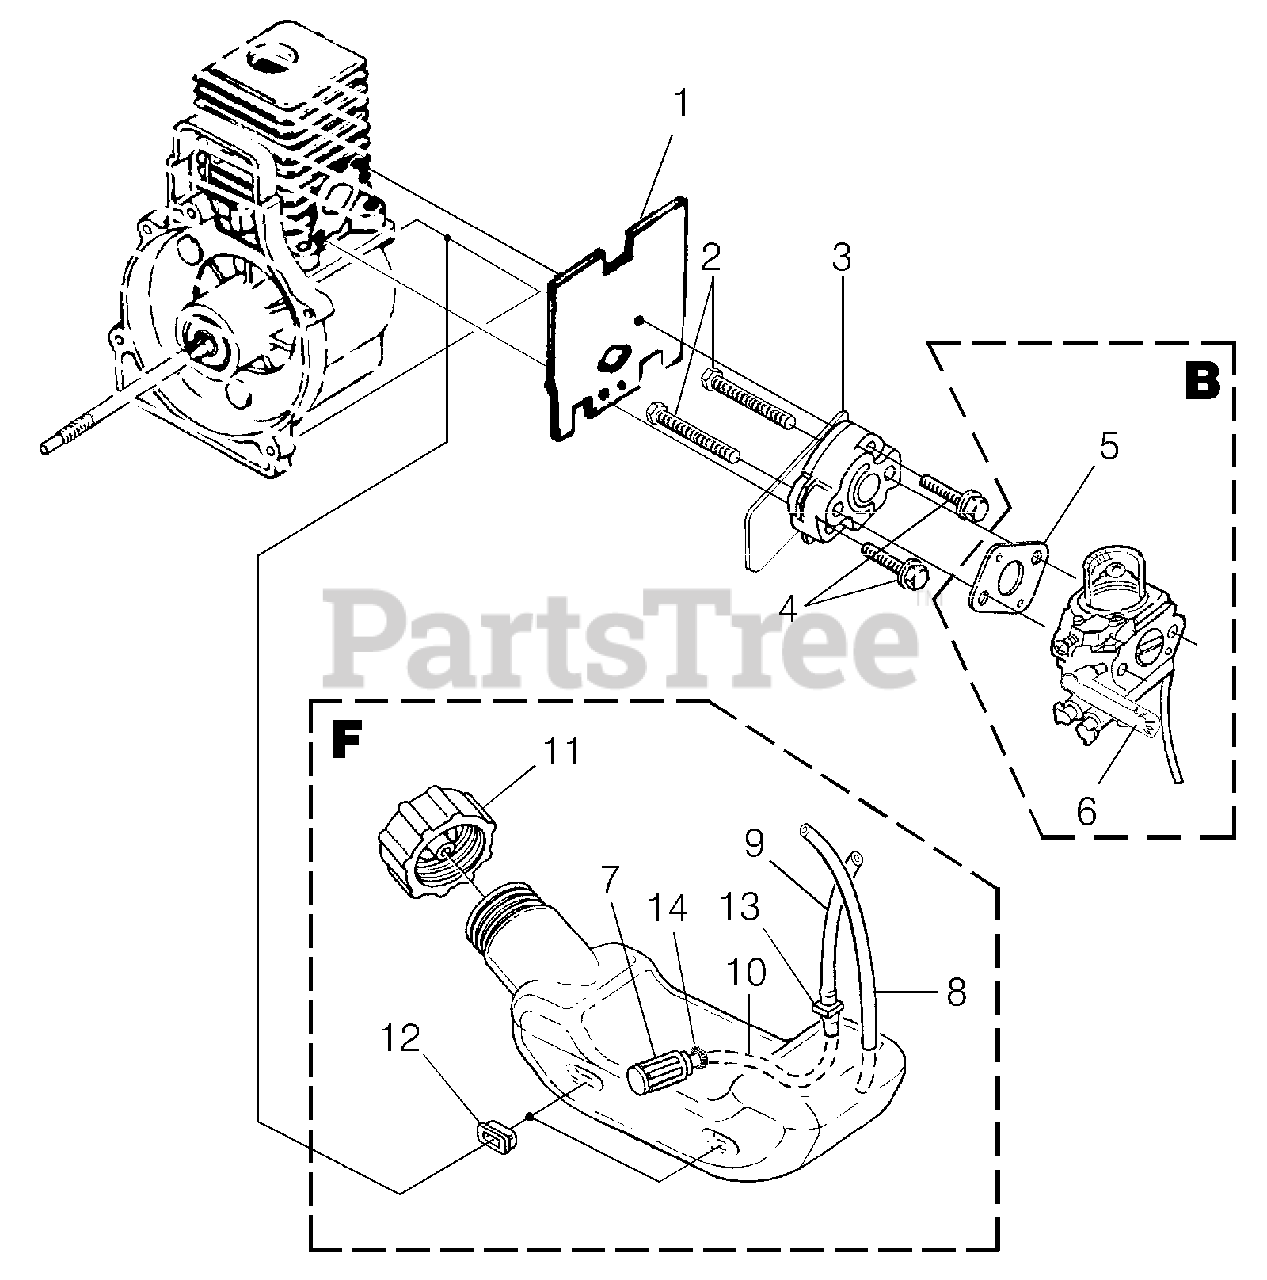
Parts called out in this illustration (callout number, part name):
1	GASKET-Heat Dam
2	SCREW-Machine (10-24 X 2 1/4")
3	HEAT DAM
4	SCREW-Sems (10-24 X 1")
5	GASKET-Carburetor
6	LEVER-Choke-Auto Zip
7	FILTER-Fuel
8	TUBING-Rubber
9	TUBING-Rubber
10	TUBING-Rubber
11	FUEL CAP
12	BUMPER-Rubber
13	FITTING-Inline
14	CLAMP
B	CARBURETOR KIT
F	FUEL TANK ASSY.
